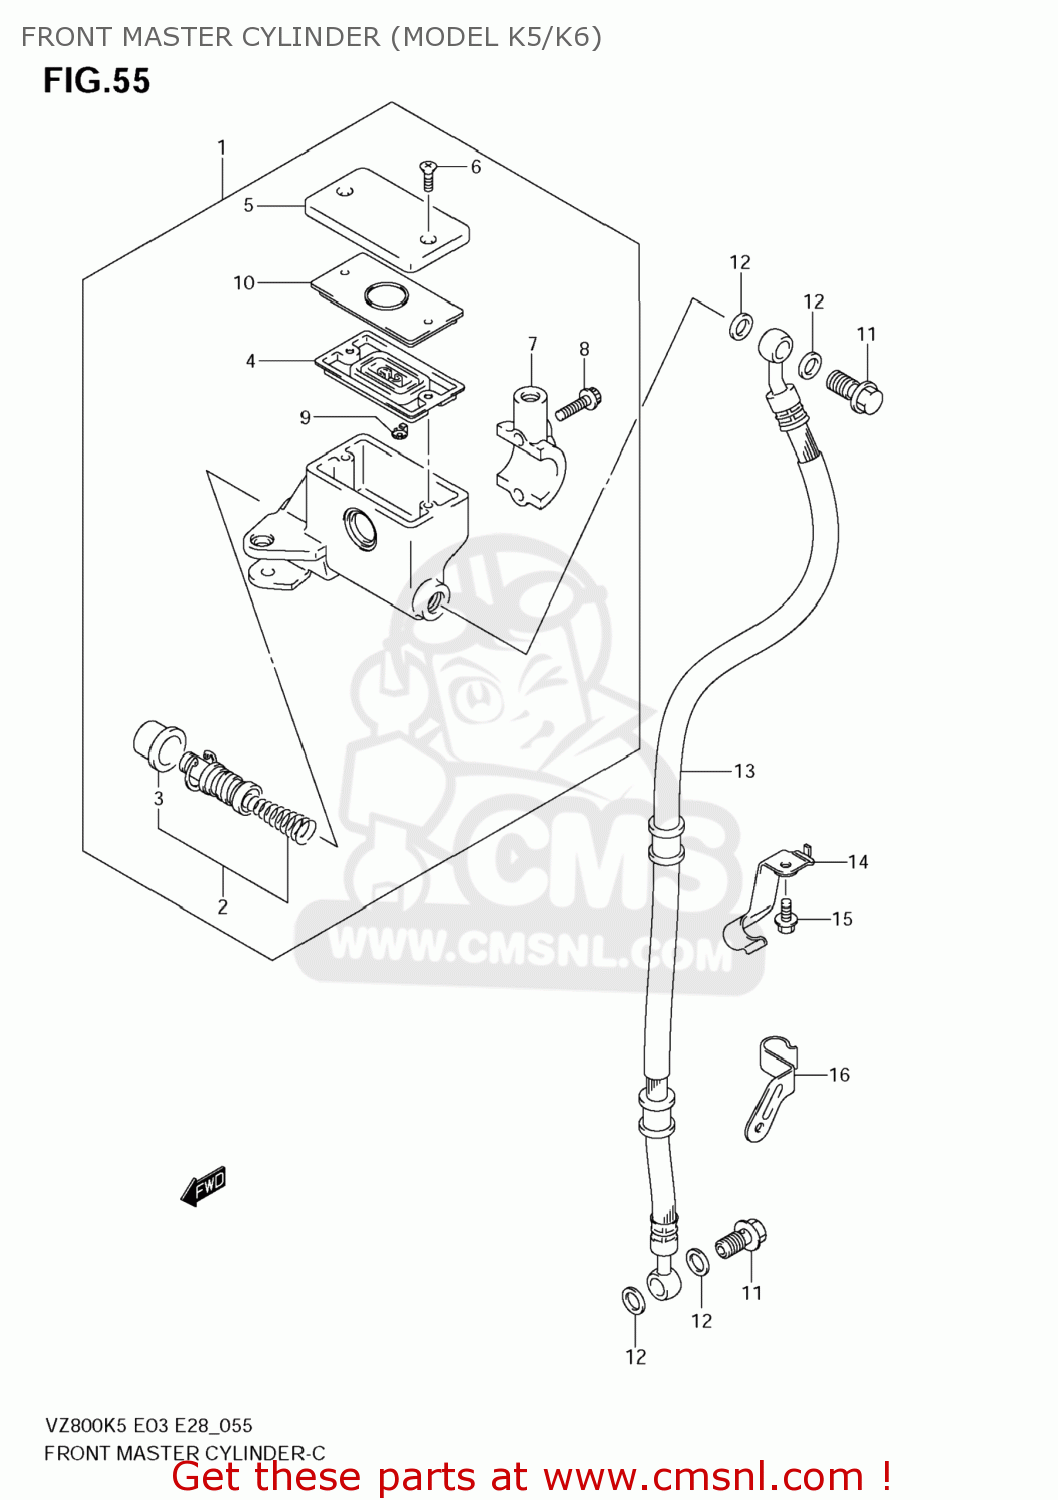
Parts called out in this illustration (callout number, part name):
1	CYLINDER ASSY,FR MASTER
2	PISTON/CUP SET
3	BOOT
4	5
5	CAP
6	SCREW
7	HOLDER
8	BOLT
9	PROTECTOR
10	PLATE,DIAPHRAGM
11	BOLT UNION
12	WASHER(10X15X1.5)
13	HOSE,FR BRAKE
14	CLAMP,FR BRAKE HOSE UPR
15	BOLT
16	CLAMP,FR BRAKE HOSE
